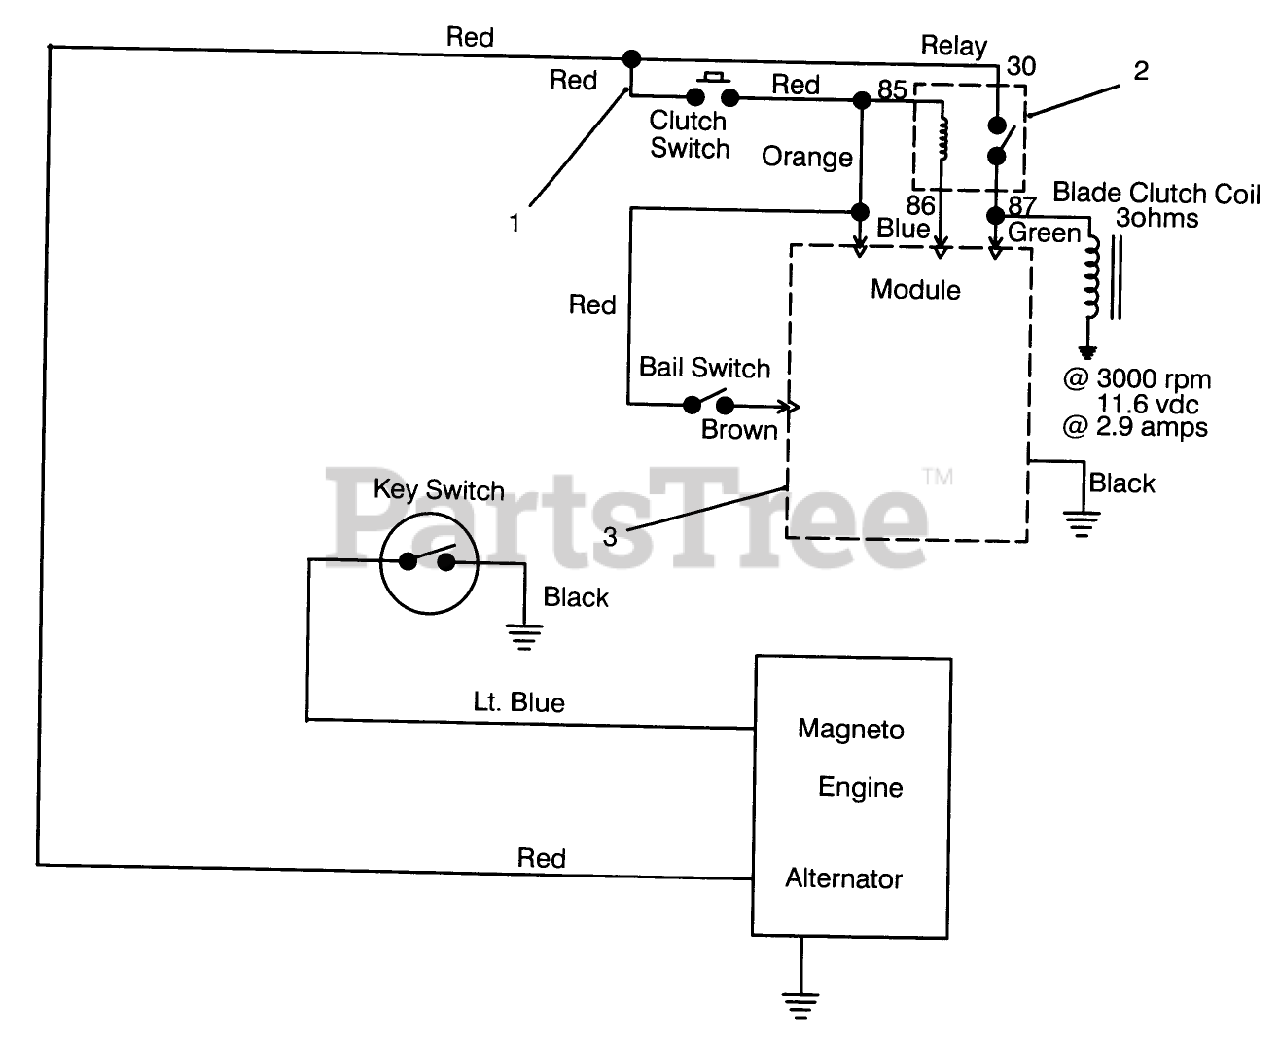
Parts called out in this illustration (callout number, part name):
1	WIRE HARNESS
2	RELAY
3	Module
